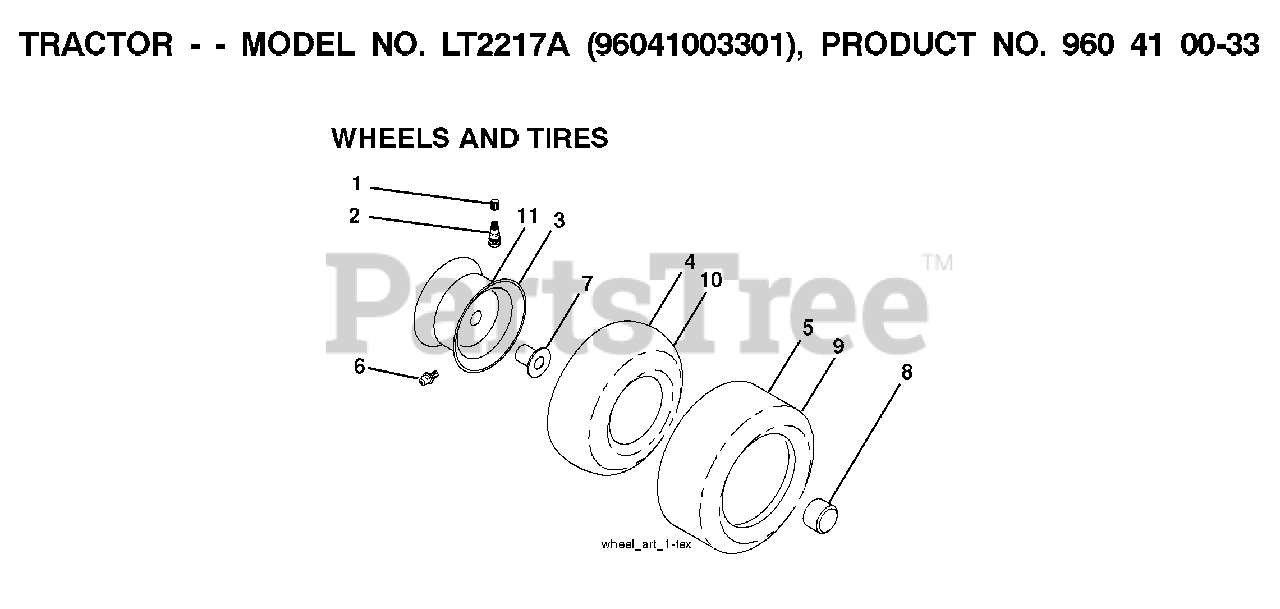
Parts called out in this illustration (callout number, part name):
1	VALVE CAP
2	VALVE STEM LT
3	RIM ASM 6" FRONT SILVER
4	TUBE.5.3/4.5/6
5	TIRE HEAVY DUTY
6	FITTING LT
7	BEARING T
8	CAP, AXLE BLK
9	TIRE HEAVY DUTY
10	TUBE
11	RIM ASM 8" REAR SILVER
